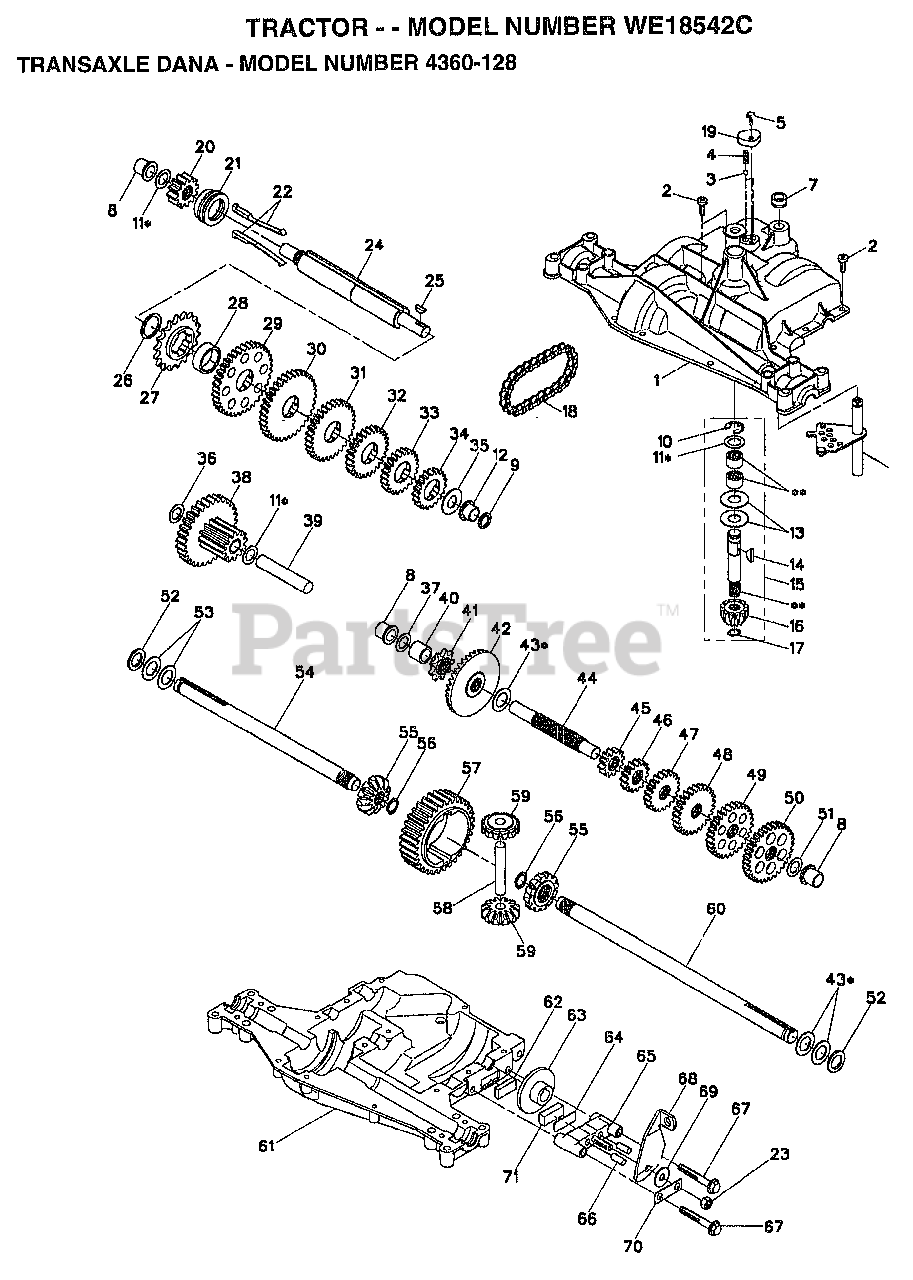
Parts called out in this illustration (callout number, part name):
1	HOUSING.UPPER(5305-P)
4	"SPRING, DETENT LT"
5	SCREW.TAPPING.1/4-20X.734
6	KIT SHIFTER ASM
9	SEAL.OIL.DAN.5508
10	RETAINING RING LT
11	ASM KIT SHIM 4689
12	BEARING.FLNG.5511
13	WASHER T
14	KEY WOODRUFF-DANA
15	INPUT SHAFT KIT 6250
16	PINION.BEVEL.12T(5620)
17	"RING,RETAINING LT"
18	"CHAIN,24 PTCH LT"
19	COVER.DETENT.(5584)
20	GEAR.SPUR.12T.(5627)
21	CLUTCH.COL.5467
22	ASM KIT CLTCH KEY
23	NUT.LOCK.5/16-24
24	SHAFT INTERM DANA
25	WOODRUFF KEY
26	"RING,RETAINING LT"
27	SPROCKET 18T T
28	SPACER YT
29	GEAR SPUR 37 TTH
30	GEAR SPUR 35 TTH
31	GEAR SPUR 30T
32	GEAR 25T LT
33	GEAR SPUR 22 TT
34	SPUR GEAR 19T
35	"WASHER, PLAIN LT"
36	WASHER 045
37	WASHER 031
38	ASSY.GEAR.6153 12T&30T
39	SHAFT IDLER
40	SPACER T
41	SPROCKET 9T LT
42	GEAR.BEVEL.36T(5621)
43	ASM KIT SHIM
44	SHAFT T
45	GEAR SPUR 12 TTH
47	GEAR SPUR 20T
48	"GEAR, SPUR 25T LT"
49	GEAR 28T T
50	"GEAR, SPUR 31T LT"
51	WASHER 060
52	NEOPRENE WASHER
53	WASHER 031
54	AXLE.LH(5528-1)
55	MITER 5270 12T.SPLINED
56	RING.RETAINING.(5270)
58	SHAFT T
59	MITER 5623.12T.IDLER
60	AXLE.RH.(5528-2) DANA
61	HOUSING.KIT (6088)
62	PUCK T
63	BRAKE DISC. T
64	SPACER LT
66	PIN T
67	SCREW.(5562) .5/16-18X2.35
69	WASHER LT
70	BRACKET, ANTI-ROTATION
71	PUCK T
